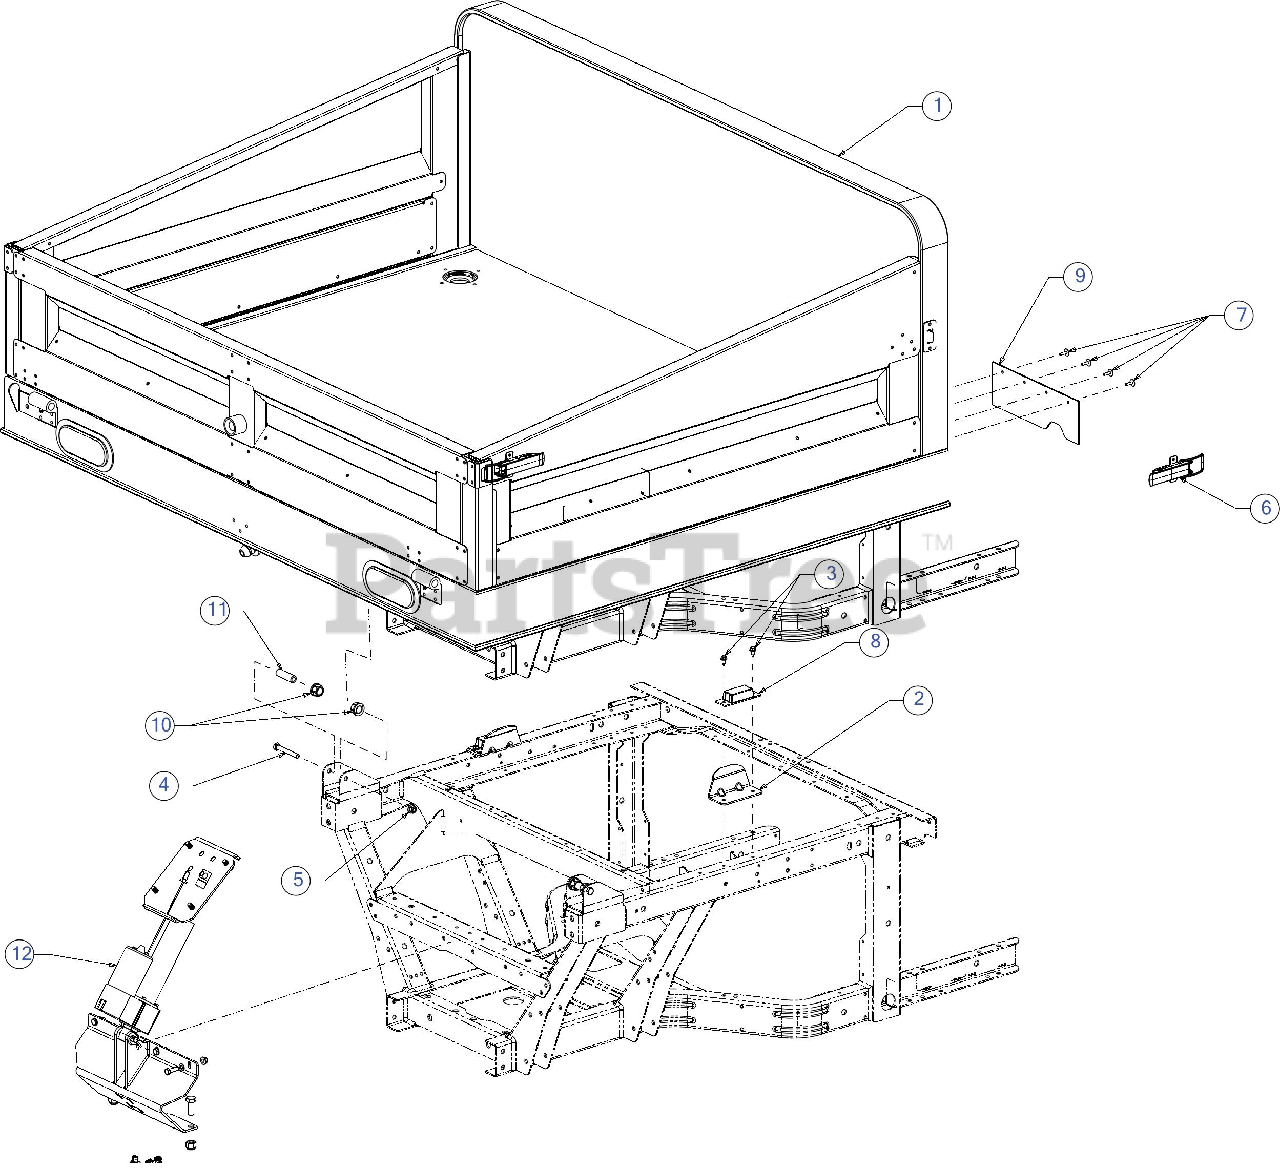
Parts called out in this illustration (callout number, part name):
1	FLAT BED ASSEMBLY
2	BED GUIDE BRACKET
3	SCREW 1/4-20X.625
4	SCREW 3/8-16 x 2.75 GR5
8	SUSPENSION BUMPER
9	REAR MUD FLAP
10	FLANGE BEARING
11	SPACER:.390 ID x .625OD x 2.03
12	BED LIFT PLATE ASSEMBLY
